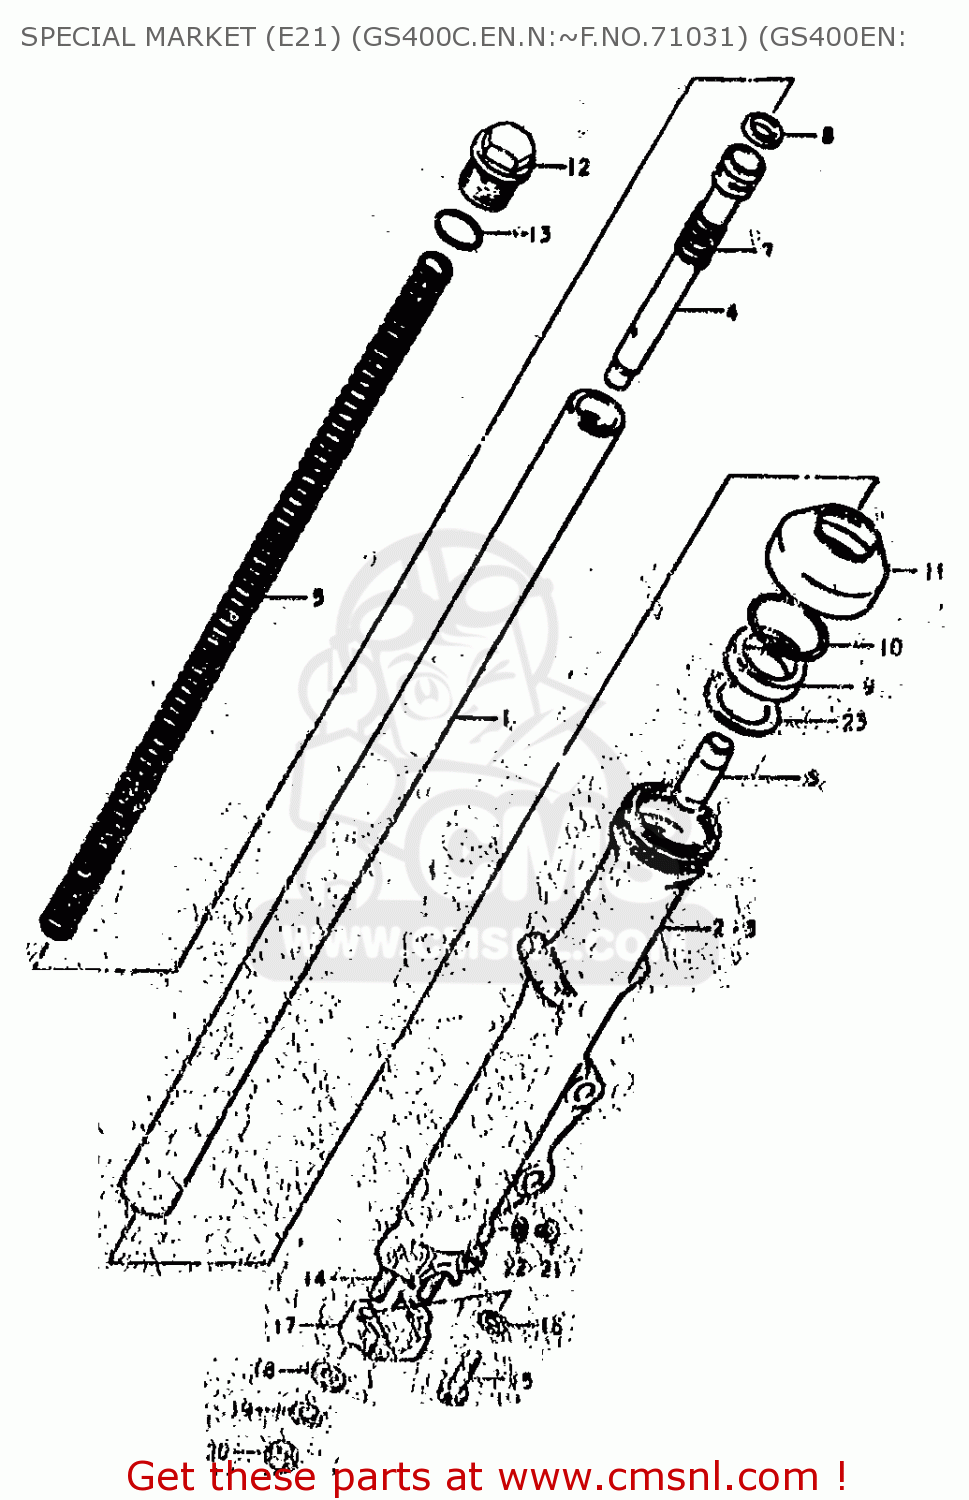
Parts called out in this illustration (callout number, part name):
1	TUBE,INNER
2	TUBE,OUTER,LEFT
3	TUBE,OUTER,RIGHT
4	CYLINDER,FRONT FORK
5	SPRING
6	PIECE,OIL LOCK
7	SPRING,REBOUND
8	RING,PISTON
9	OIL SEAL,FRONT FORK
10	CIRCLIP,FORK OIL SEAL
11	BOOT
12	BOLT
13	O RING
14	STUD 8X25
15	BOLT
16	GASKET (NAS)
17	HOLDER,AXLE
18	WASHER
19	LOCK WASHER
20	NUT
21	SCREW
22	GASKET (NAS)
